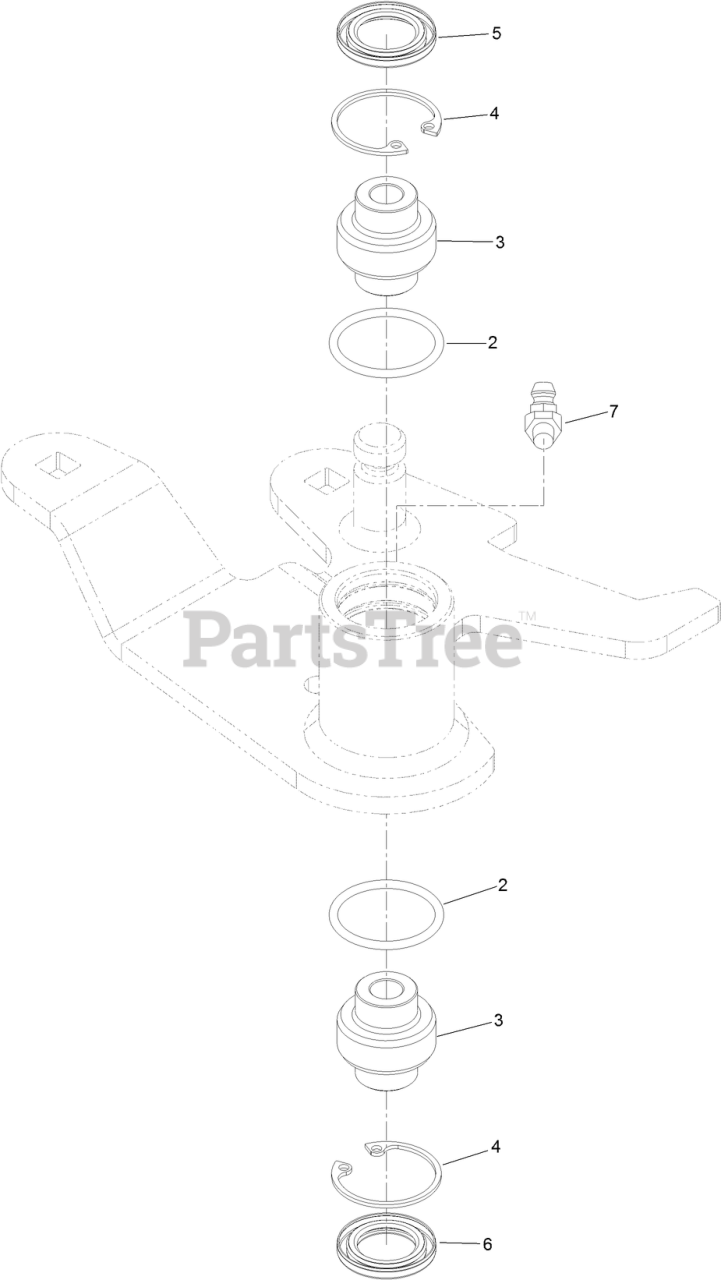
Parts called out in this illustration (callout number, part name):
2	O-RING
3	BEARING-SPHERICAL
4	RING-SNAP
5	SEAL-LIP, SINGLE
6	SEAL-LIP, DOUBLE
7	FITTING-LUBE, 45 DEG
